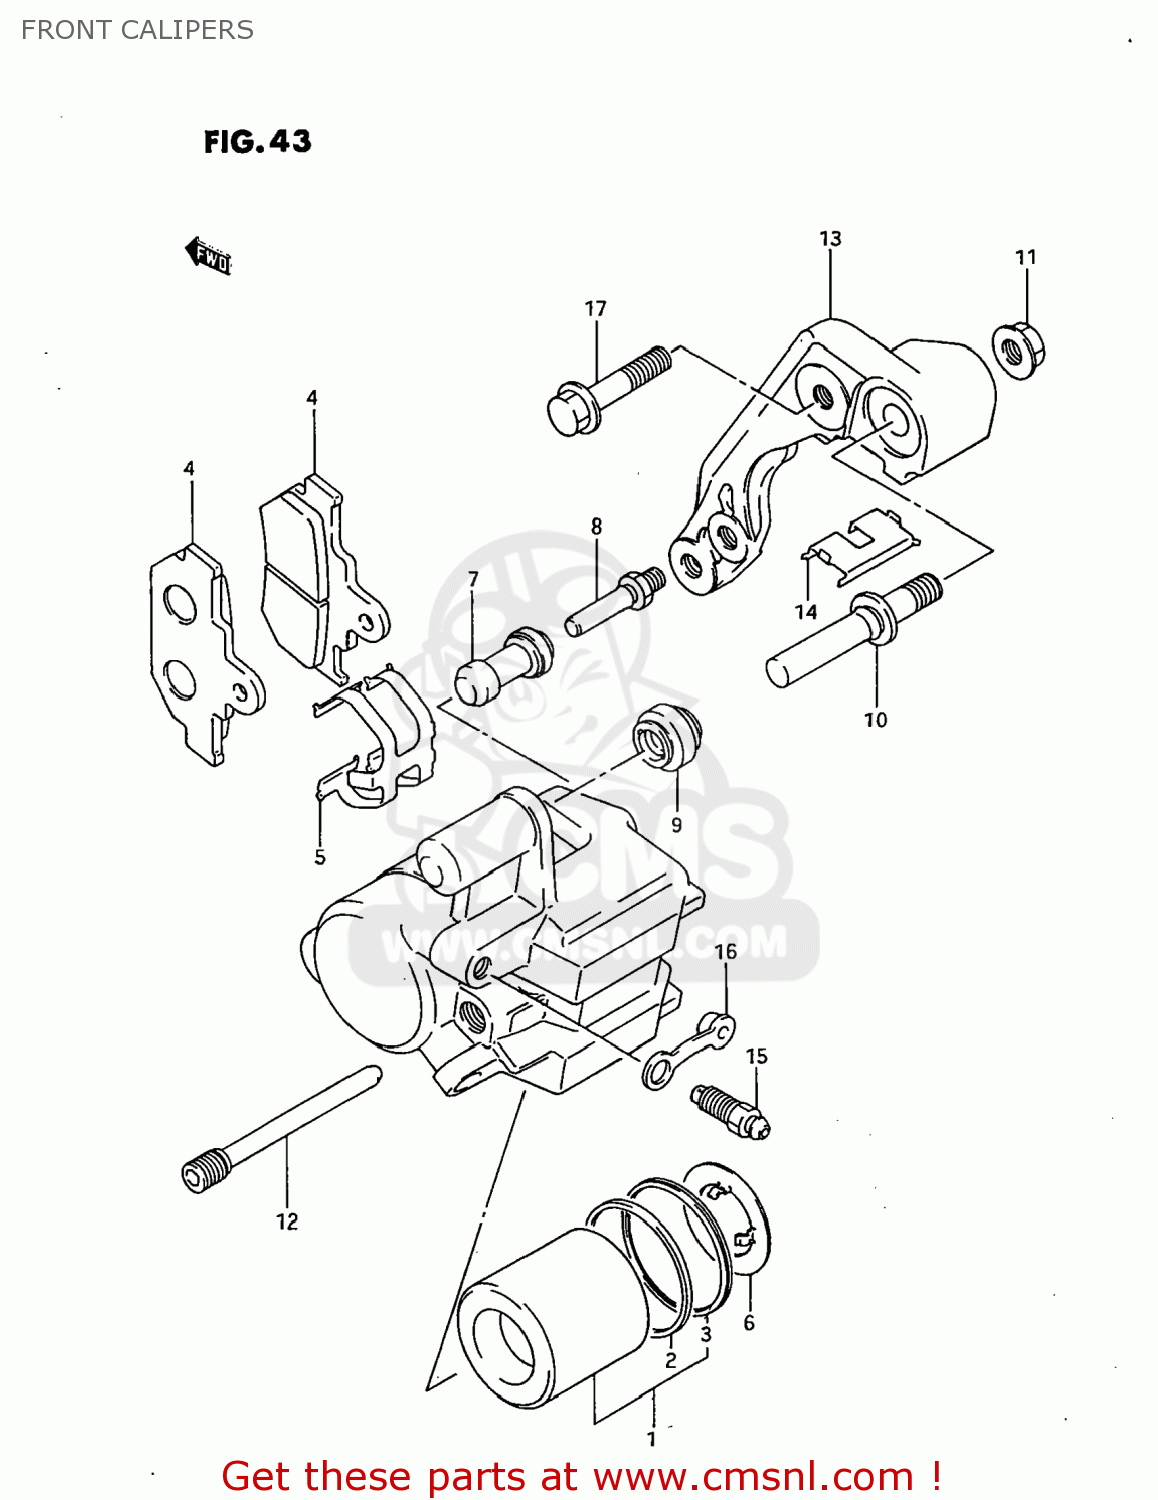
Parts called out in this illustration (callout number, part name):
1	PISTON SET,CALIPERS
2	SEAL,PISTON
3	DUST SEAL,PISTON
4	PAD
5	SPRING,PAD
6	SHIM
7	BOOT
8	PIN,BOLT
9	BOOT
10	PIN,SLIDE
11	NUT,SLIDE PIN
12	PIN,HANGER
13	BRACKET
14	RETAINER
15	BLEEDER
16	CAP,BLEEDER
17	BOLT(8X35)
